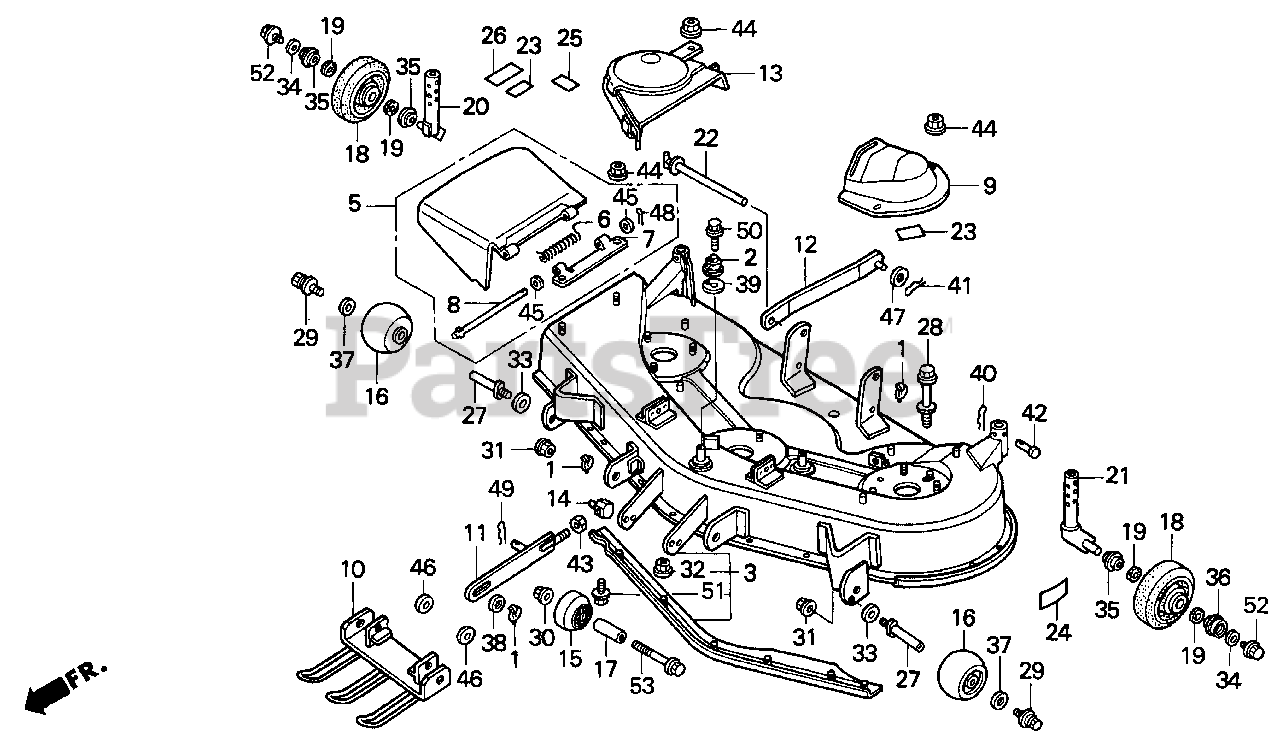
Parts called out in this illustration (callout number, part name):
1	LINCHPIN ASSY.
2	RUBBER (LOWER)
3	HOUSING, CUTTER *NH190M* (VINTAGE GRAY METALLIC)
5	ADAPTER, DISCHARGE
6	SPRING, DISCHARGE ADAPTER
7	HINGE, DISCHARGE ADAPTER
8	PIN, DISCHARGE ADAPTER
9	COVER, L. BELT
10	PLATE, FR. LINK (LOWER)
11	LINK, FR. DECK
12	LINK, RR. DECK
13	STOPPER, BELT
14	PIN, FR. LINK ADJUSTING
15	ROLLER, ANTI-SCALP
16	ROLLER, ANTI-SCALP
17	COLLAR, ANTI-SCALP ROLLER
18	ROLLER ASSY., GAUGE
19	DUST SEAL, GAUGE ROLLER
20	ARM, R. GAUGE ROLLER
21	ARM, L. GAUGE ROLLER
22	SHAFT, RR. LINK
23	LABEL A, WARNING (ENGLISH)
24	MARK, INCH SIZE (46)
25	MARK, HEIGHT ADJUSTING (ENGLISH)
26	MARK, DANGER
27	SHAFT, ANTI-SCALP ROLLER
28	BOLT, BELT STOPPER
29	BOLT, WHEEL
30	NUT, U (10MM)
31	NUT, SELF-LOCK (12MM)
32	NUT, FLANGE (8MM)
33	WASHER, THRUST (12MM)
34	WASHER (10.5X27X4)
35	COLLAR, GAUGE ROLLER
36	COLLAR, GAUGE ROLLER
37	WASHER (8MM)
38	WASHER, PLAIN (14MM)
39	WASHER (40MM)
40	PIN, SNAP (7MM)
41	PIN, LOCK (14MM)
42	PIN B, WHEEL
43	NUT, HEX. (12MM)
44	NUT, FLANGE (8MM)
45	WASHER, PLAIN (6MM)
46	WASHER, PLAIN (12MM)
47	WASHER, FLAT (14MM)
48	PIN, COTTER (2.0X15)
49	PIN, LOCK (12MM)
50	BOLT, FLANGE (6X14)
51	BOLT, FLANGE (8X16)
52	BOLT, FLANGE (10X16)
53	BOLT, FLANGE (10X110)
